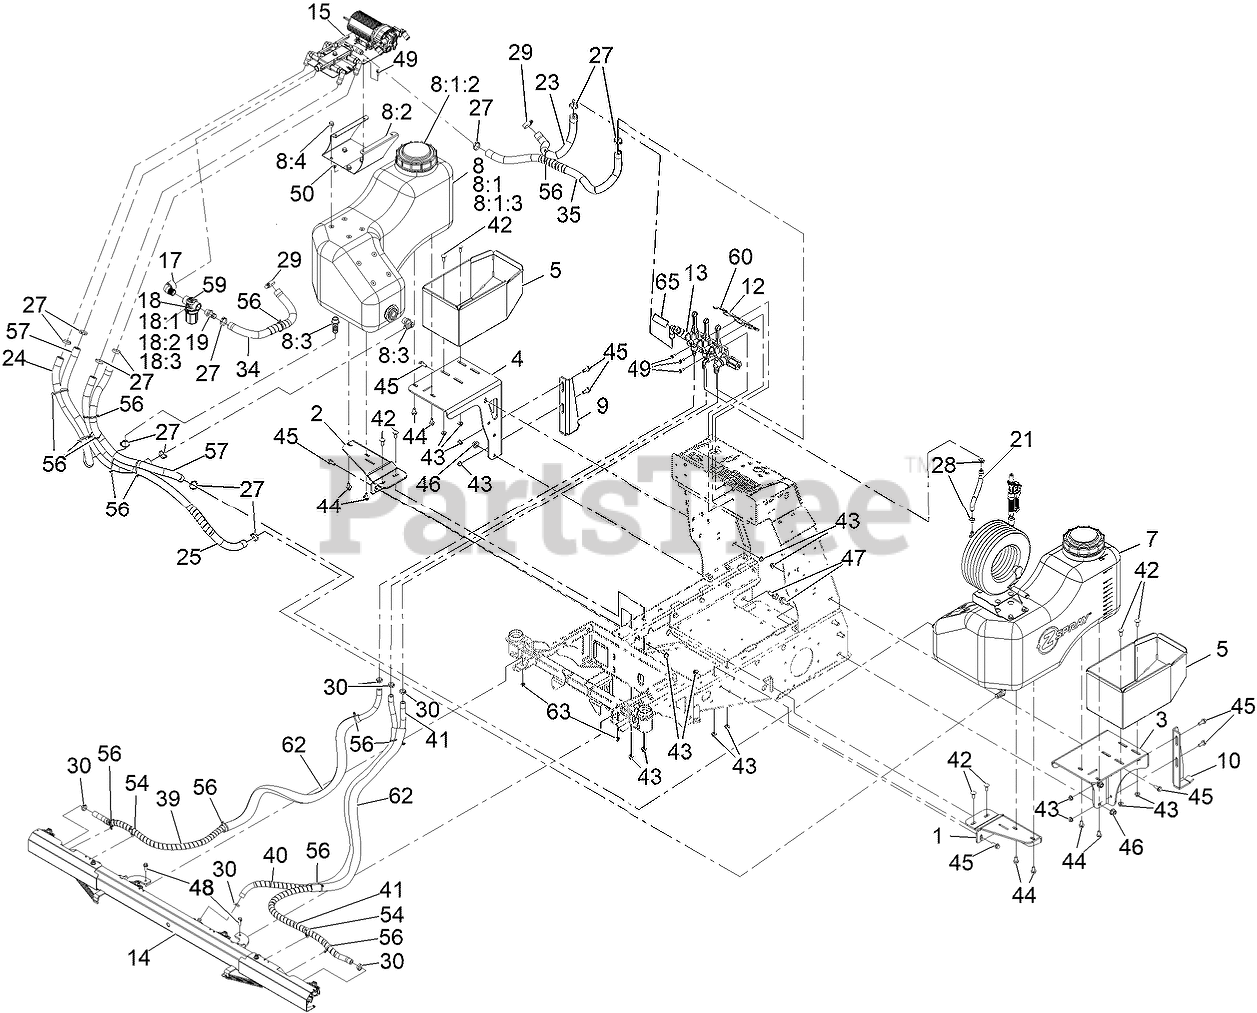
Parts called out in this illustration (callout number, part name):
1	Mount-Tank, LH Wing
2	Mount-Tank, RH Wing
3	Mount-Box, Lt Fert
4	Mount-Box, Rt Fert
5	BOX-FERT
7	ASM-Tank, Hose Reel
8	ASM-Tank, Rt
8:1	ASM-TANK, RT
8:1:2	CAP-TANK, SPRAY
8:1:3	Fitting-Bulkhead
8:2	FITTING-ELBOW, 90
8:3	PLATFORM, LIQUID VALVE MO
8:4	Screw-HHF
9	Bracket-Anti-Tip, Rt
10	Bracket-Anti-Tip, Lt
12	Bracket-Manifold
13	ASM-Manifold
14	ASM-Boom, Spray
15	ASM, Liquid Valve
17	ELBOW-90DEG
18	STRAINER-INLINE
18:1	BOWL-STRAINER
18:2	GASKET-HEAD, LINE STRAINE
18:3	Screen-Strainer, 50 Mesh
19	HOSEBARB
21	Hose-Spray
23	Hose-Spray
24	Hose-Spray
25	Hose-Spray, Wrapped
27	Clamp-Oetiker, 167
28	CLAMP-OETIKER, 167
29	CLAMP-HOSE
30	CLAMP-OETIKER, 167
34	Hose-Spray, Wrapped
35	Hose-Spray, Wrapped
39	Hose-Spray, Wrapped
40	Hose-Spray, Wrapped
41	Hose-Spray, Wrapped
42	SCREW-CARR
43	Nut-Hex Flange
44	SCREW-HHF
45	SCREW-HHF
46	NUT-HEX FLANGE
47	SCREW-HHF
48	SCREW-HHF
49	Screw-HHF
50	Nut-Hex Flange
54	CLIP-TIE
56	TIE-CABLE
57	Hose-Spray
59	DECAL-CAP, STRAINER
60	Decal-Valve, Boom
62	Guard-Mesh
63	Nut-Hex Flange
65	GAUGE
